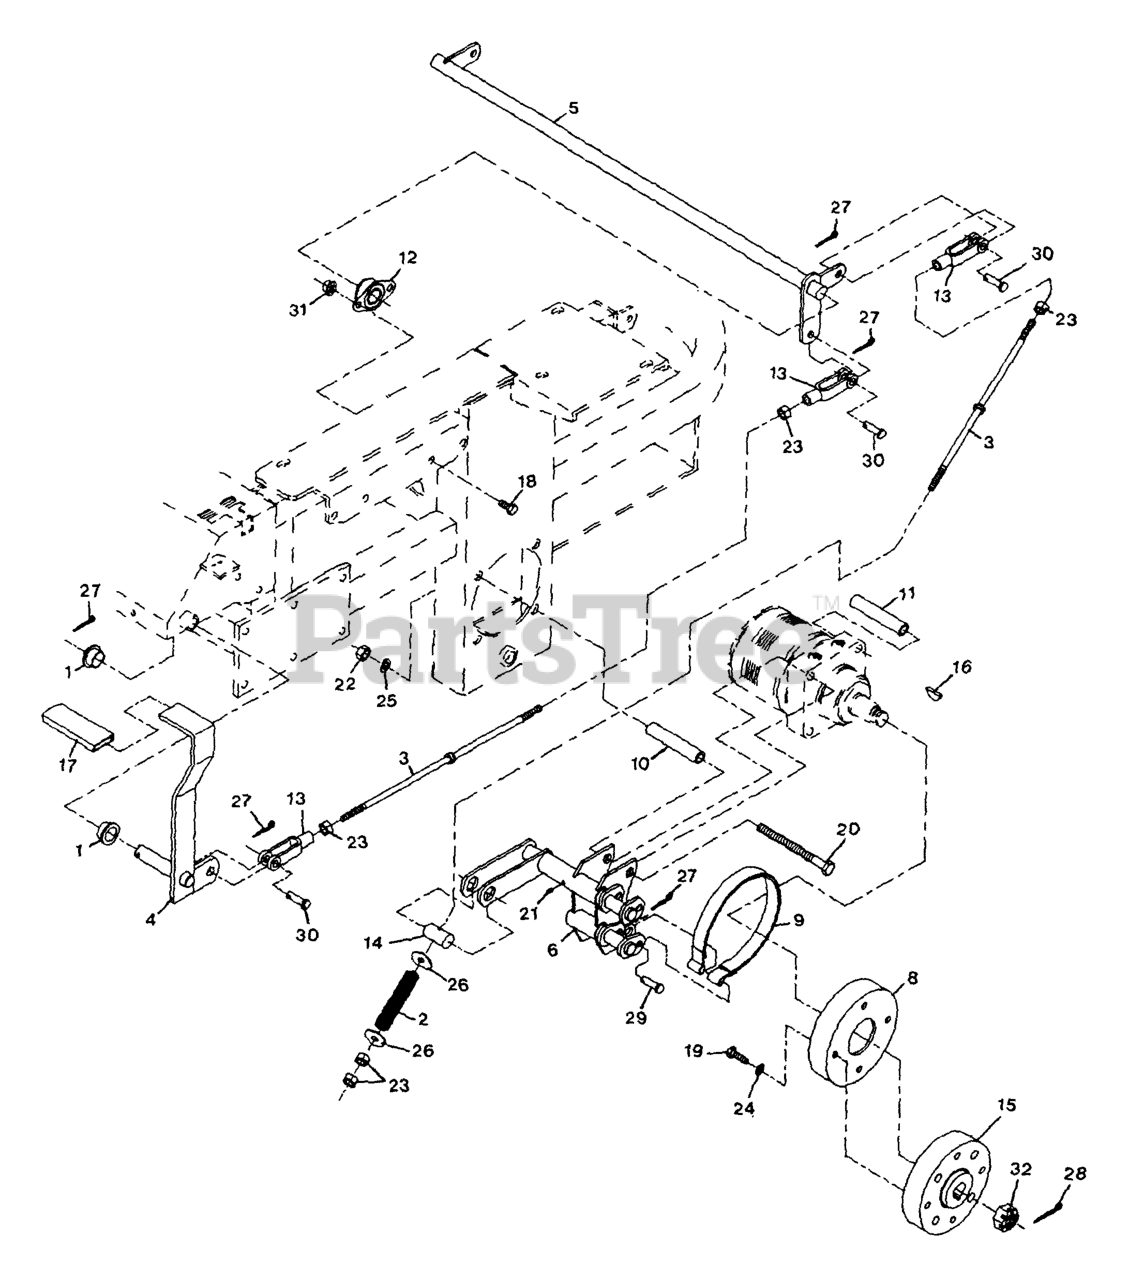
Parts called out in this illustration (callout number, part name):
1	BEARING-CONTROL
2	SPRING,COMPRESSION
2	SPRING-BRAKE
5	SHAFT-BRAKE
10	SPACER-WHEEL, SHORT
12	BEARING-FLANGE, SIDE
13	YOKE-LINKAGE, BRAKE
14	PIN-TRUNION
17	GRIP-LEVER
28	PIN-COTTER
29	PIN,CLEVIS 3/8X2
30	PIN-CLEVIS
